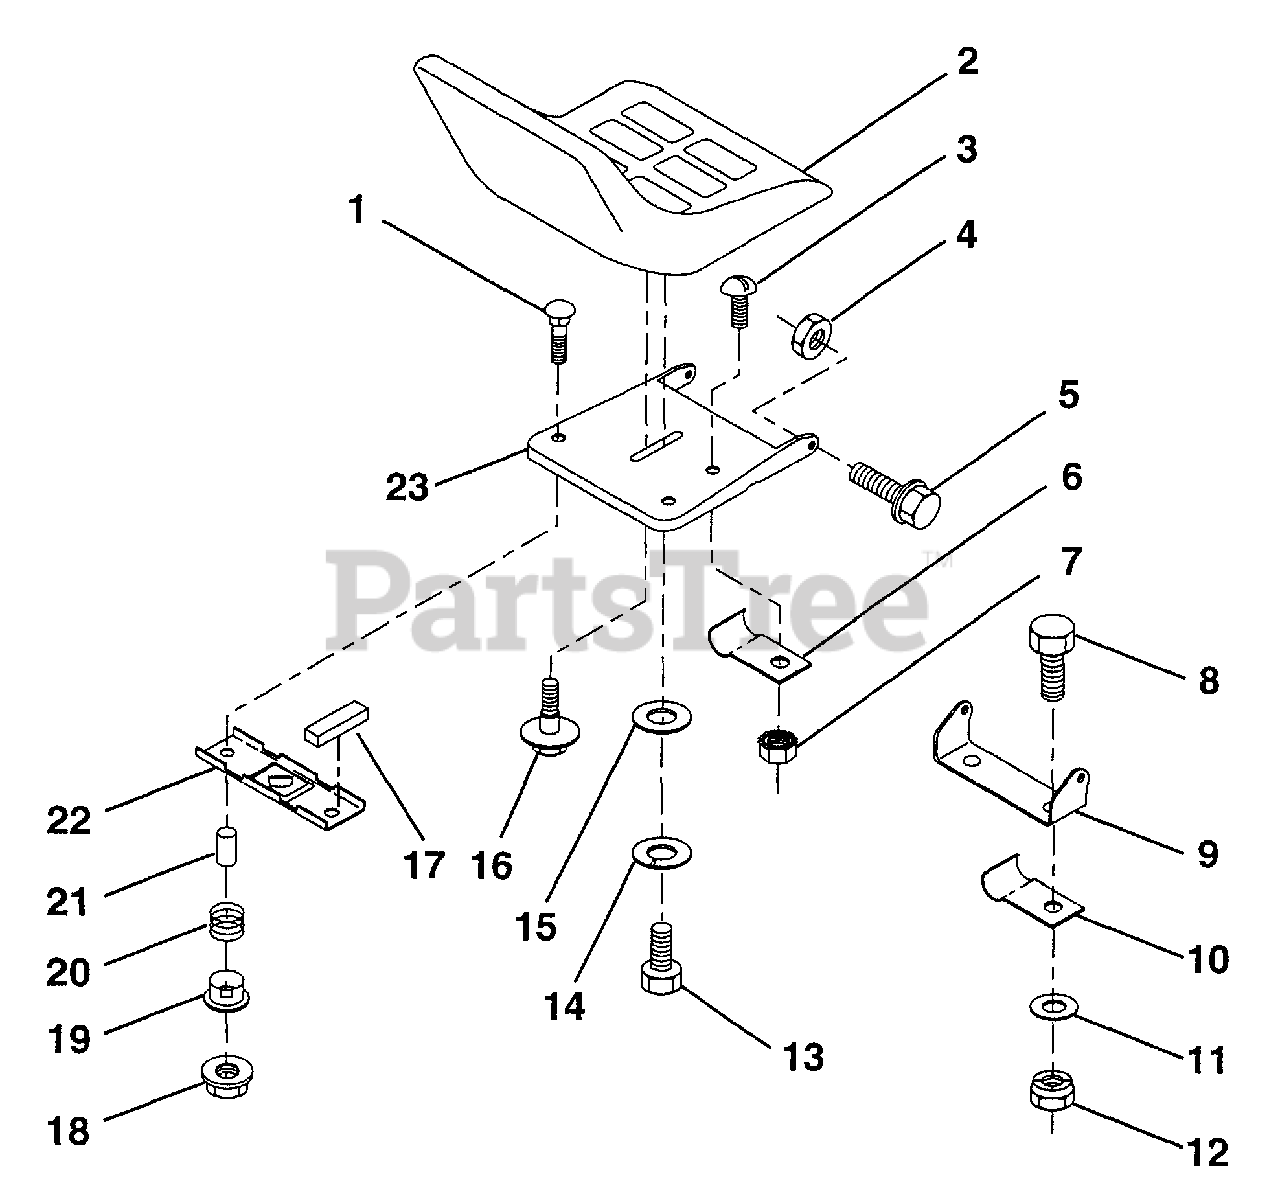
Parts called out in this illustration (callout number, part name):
1	Bolt, Carriage 1/4-20 x 1-3/8
2	Seat
3	Screw, Slotted Pan Head # 10-32 x 1/2
4	Nut, Crownlock 5/16-18
5	Bolt, Shoulder 5/16-18 UNC
6	Clip, Insulated
7	Nut, Hex, Keps #10-32 UNF
8	Bolt, Hex, Fin. 3/8-16 UNC x 3/4
9	Bracket, Pivot, Seat
10	Clip, Insulated
11	Washer 12/32 x 2 x 10 Gauge
12	Nut, Crownlock 3/8-16 UNC
13	Bolt, Hex, Fin. 1/2-13 UNC x 7/8 Grade 5
14	Washer, Lock, Heavy Helical Spring
15	Washer 17/32 x 1-3/16 x 12 Ga.
16	Bolt, Shoulder
17	Strip, Foam
18	Nut, Hex, Large, Flangelock
19	Bushing, Snap
20	Spring, Compression
21	Spacer, Split
22	Bracket, Switch Mounting
23	Pan, Seat
